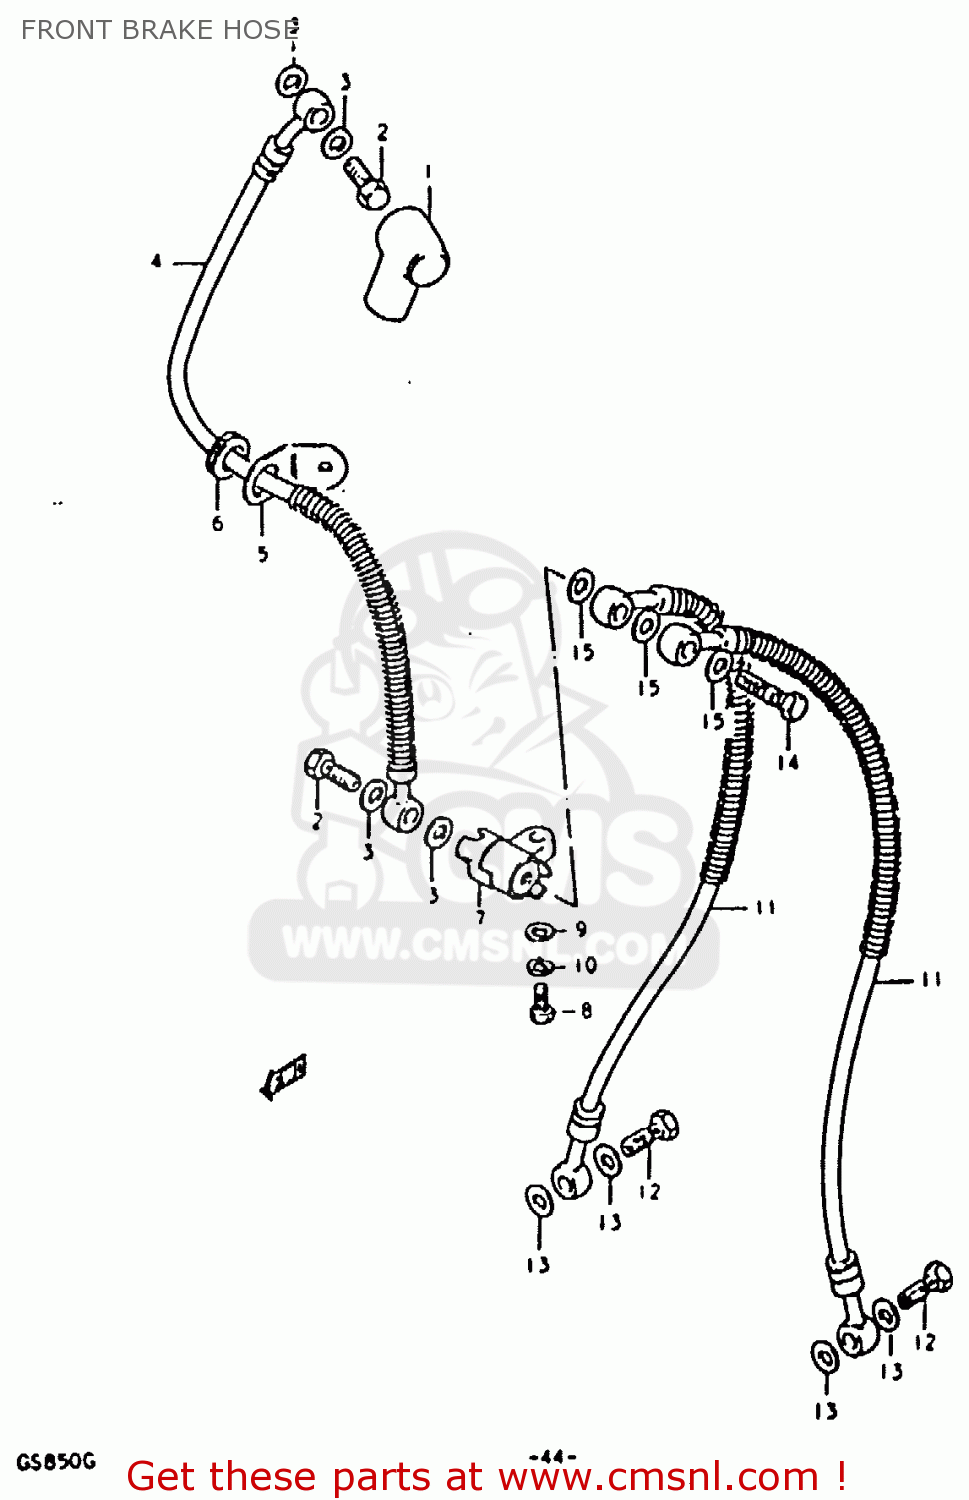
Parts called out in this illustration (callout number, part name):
1	BOOT,MASTER CYLINDER
2	BOLT UNION
3	WASHER
4	HOSE,FRONT BRAKE
5	GUIDE,BRAKE HOSE
6	GROMMET
7	JOINT,BRAKE HOSE
8	BOLT
9	WASHER
10	LOCK WASHER
11	HOSE,FRONT BRAKE
12	BOLT UNION
13	WASHER
14	BOLT UNION
15	WASHER
